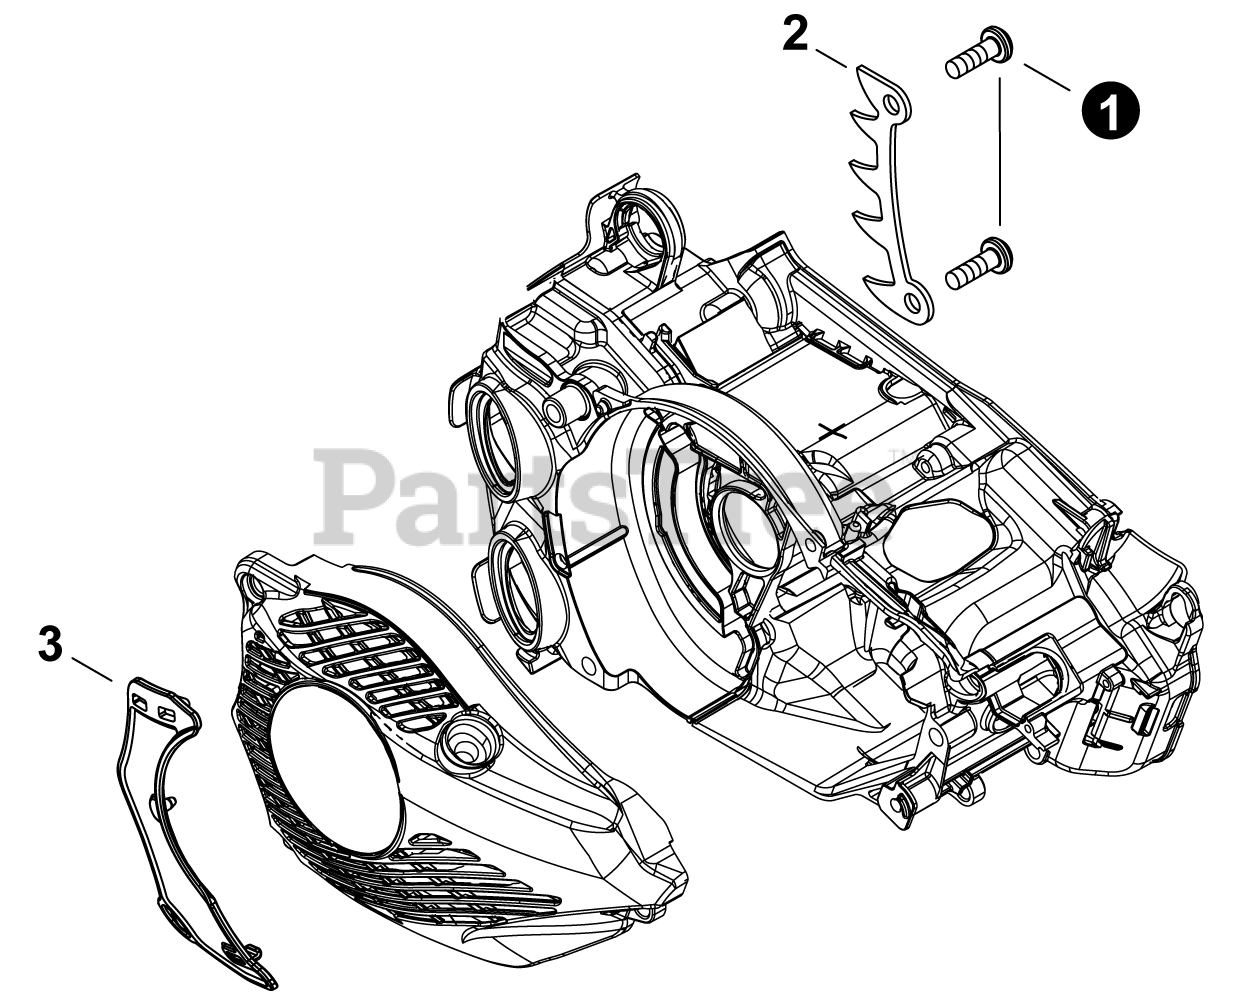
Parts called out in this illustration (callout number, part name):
1	BOLT, TORX 5x12
2	SPIKE, BUMPER
3	SHIELD, SNOW
